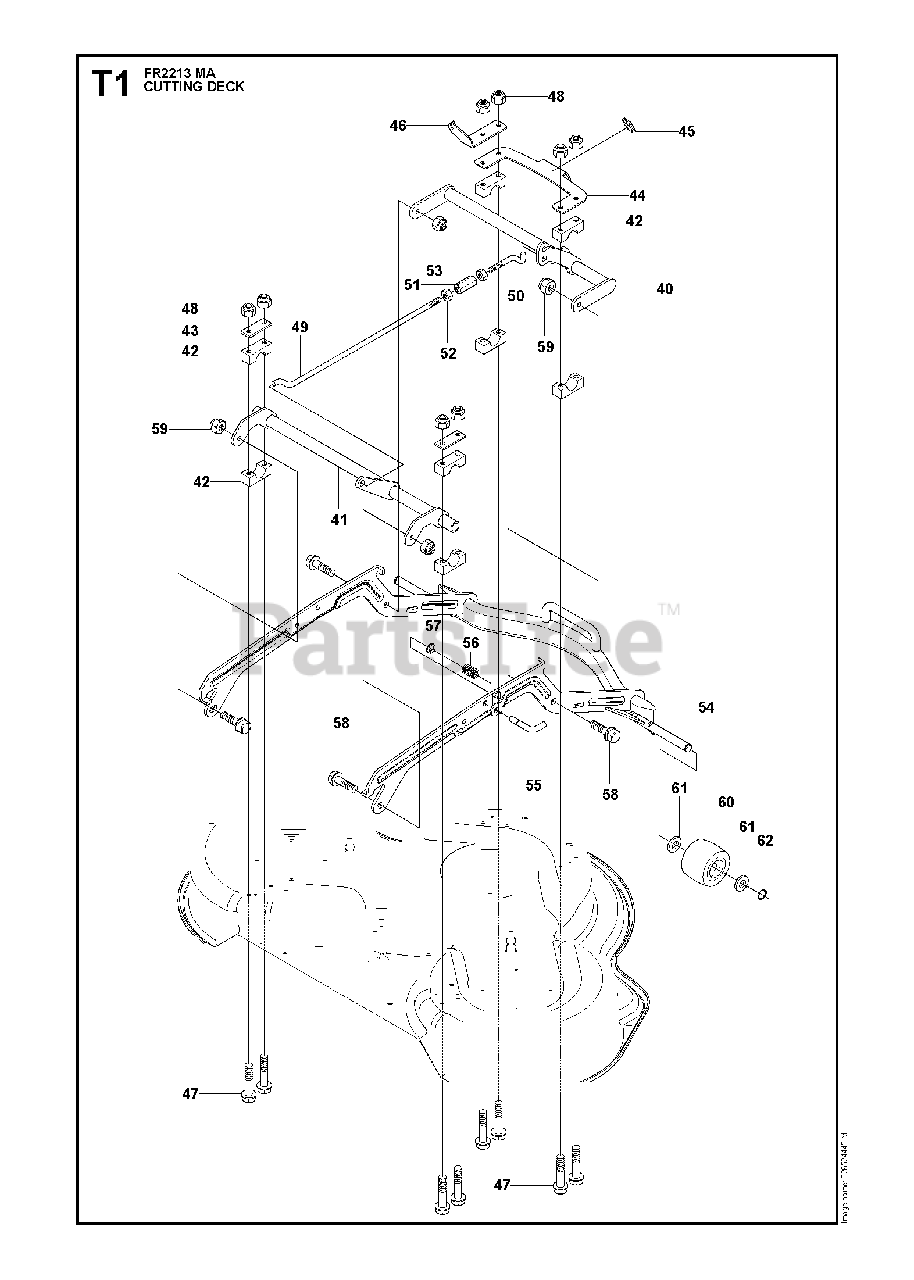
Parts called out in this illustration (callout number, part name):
3	NUT
6	RP SPINDLE ASSY
7	SHAFT
8	BEARING
9	SPACER
10	BEARING HOUSING
13	BEARING
14	SPACER
15	BEARING HOUSING
16	BOLT
17	WASHER BRB 8.4X17
18	LOCKNUT M8
19	PULLEY
20	KEY
22	PULLEY
23	WASHER
24	BOLT
27	BOLT
29	BRACKET
30	PULLEY
31	SPACER
32	BOLT
33	WASHER
34	SCREW
35	LOCKNUT M8
36	SPRING
39	SCREW
42	BEARING
43	PLATE
45	BRACKET
47	BOLT
48	LOCKNUT M8
52	NUT
53	NUT
57	E-RING
58	BOLT
59	LOCKNUT M8
60	DECK ROLLER, FRONT
61	WASHER
62	RETAINING RING SGA 15
63	DECAL
